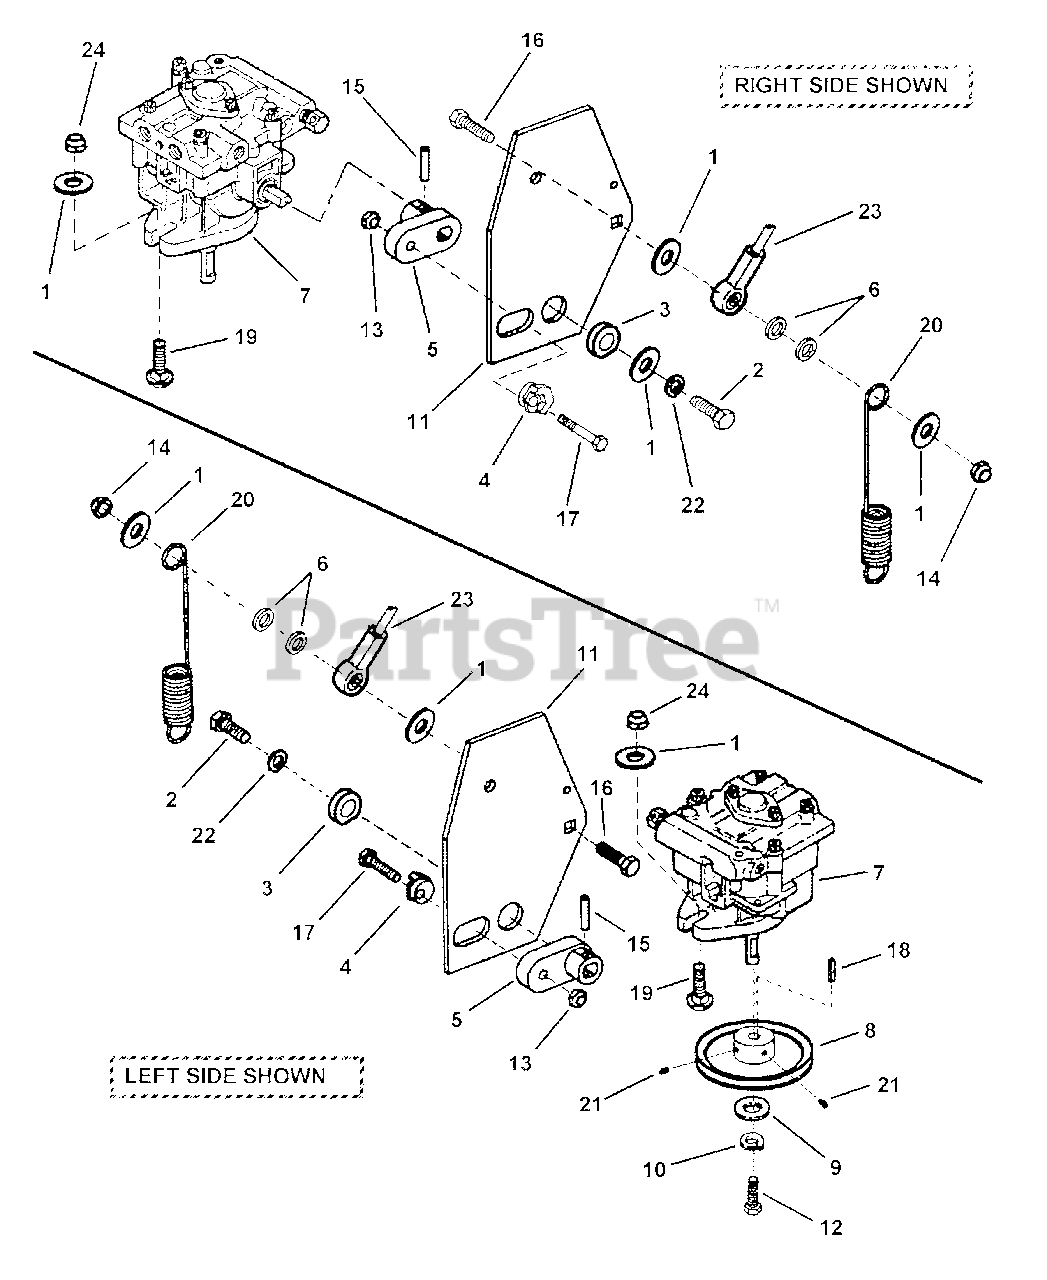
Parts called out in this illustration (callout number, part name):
1	WASHER, 3/8" I.D. x 7/8" O.D. x 1/16" Flat
2	BOLT, 5/16-18 X 3/4 GD5
3	SPACER, Blade Hub
4	ECCENTRIC
5	ARM, Pump
6	BUSHING, Spring
7	HYDRAULIC PUMP
8	PULLEY, 5.5 w/Set Screws
9	WASHER, 1/4" Flat
10	WASHER, 1/4" I.D. Split Lock
11	SHIFT ARM, Pump
12	SCREW, M6 1.0X12MM, Hex Head, CZ
13	NUT, 1/4-20 Hex Top Lock, GR B
14	NUT, 5/16-18 Hex Center Lock, GR 5 or B
15	ROLL PIN, 5mm x 25mm
16	BOLT, 5/16-18 X 1-1/4 GD5 YZ
17	SCREW, 1/4-20 x 1-1/4, Hex Head Cap, GR 5
18	KEY, M5 x M20
19	BOLT, 3/8-16 x 1-1/4" Short Neck Carriage, GR 5
20	SPRING, Hydro
21	SET SCREW, 1/4-20 X 3/8" CONE
22	WASHER, .32 x .58 x .08 Split Lock
23	ROD END, Pump Control Linkage (5/16-24 thread)
24	NUT, 3/8-16, HEX TOP LOCK
